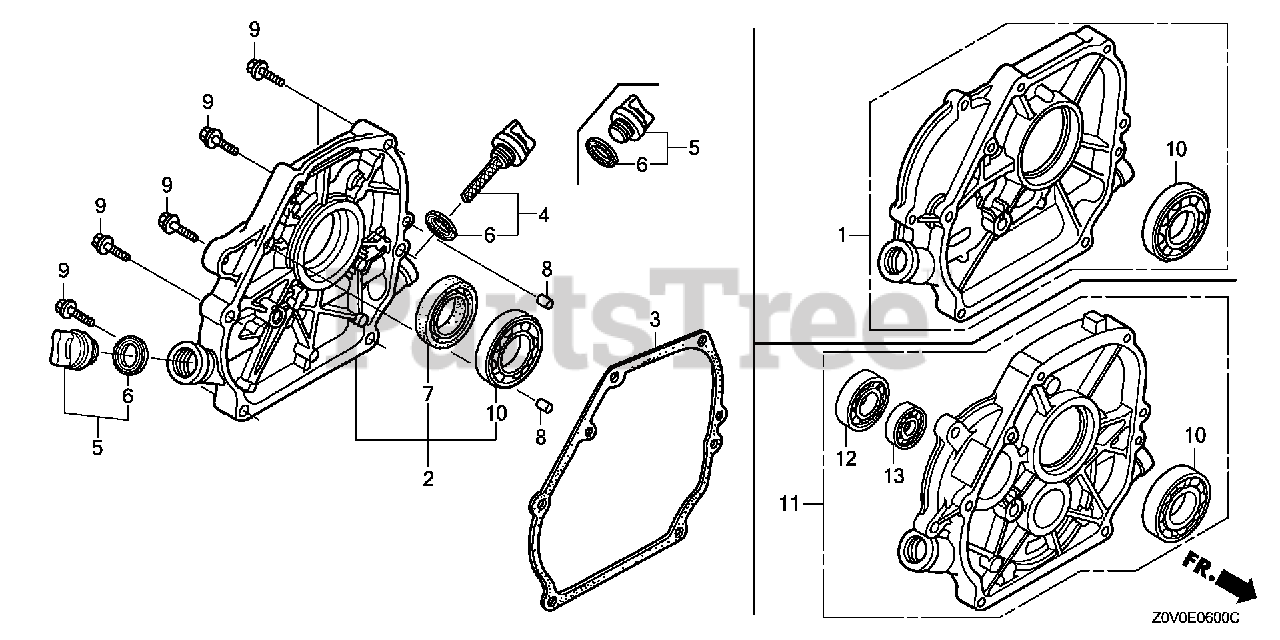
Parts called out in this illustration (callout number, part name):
2	COVER ASSY., CRANKCASE
3	GASKET, CASE COVER (NON-ASBESTOS)
4	CAP ASSY., OIL FILLER (GAUGE)(GRAY)
5	CAP ASSY., OIL FILLER (BLACK)
6	GASKET, OIL FILLER CAP
7	OIL SEAL (25X41X6) (NOK)
8	PIN, DOWEL (8X14)
9	BOLT, FLANGE (8X32)
10	BEARING, RADIAL BALL (6205)
